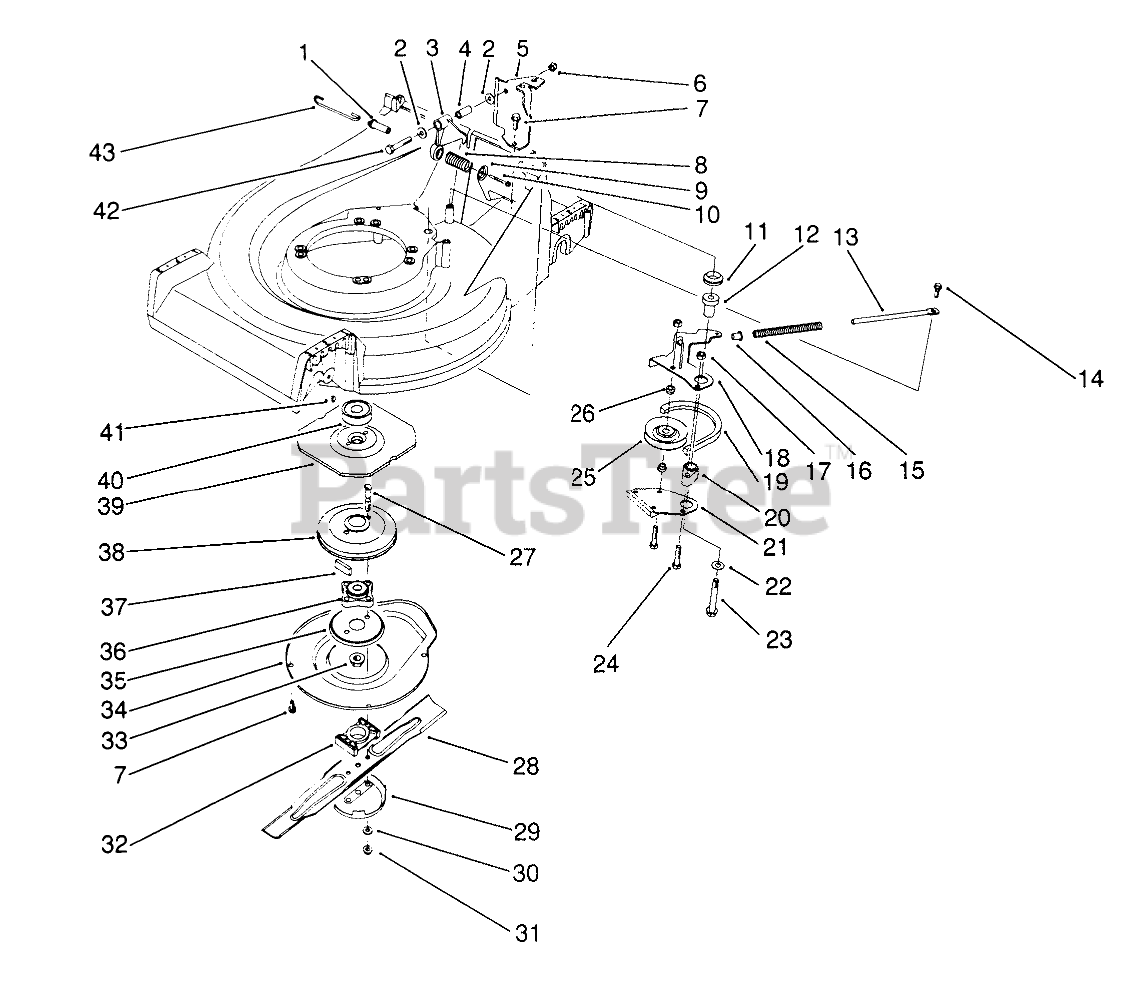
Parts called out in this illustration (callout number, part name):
1	SPRING PIN
2	WASHER-PLAIN
3	CRANK
4	STRAIGHT BUSHING
5	Bracket-Cable Support
7	SCREW-HWHTF
8	COMPRESSION SPRING
9	RETAINER-SPRING
10	SCREW-HWHTF
11	V-RING SEAL
12	BBC PM BUSHING
13	SPRING ROD
14	SCREW-SHOULDER
15	COMPRESSION SPRING
16	SPACER
17	NUT-LOCK, NI
18	Lever
19	V-BELT
20	BRAKE PLATE HUB
21	BRAKE SHOE
22	WASHER-PLAIN
23	3/8-16 X 2-3/4 CAPSCR
24	SCREW-HH
25	PULLEY-IDLER
26	IDLER PULLEY HUB
27	BOLT-BLADE
28	Key
29	Anti Scalp Cup
30	WASHER
31	NUT-LOCK
32	SPACER-BLADE
33	NUT-LOCK, NI
34	Cover
35	Screen-BBC
36	HUB ASM
37	DAMPENER-VIBRATION
38	BRAKE DRUM
39	FLYWHEEL - BBC
40	PULLEY
41	KEY-WOODRUFF
42	SCREW-HH
43	CONTROL LINK
